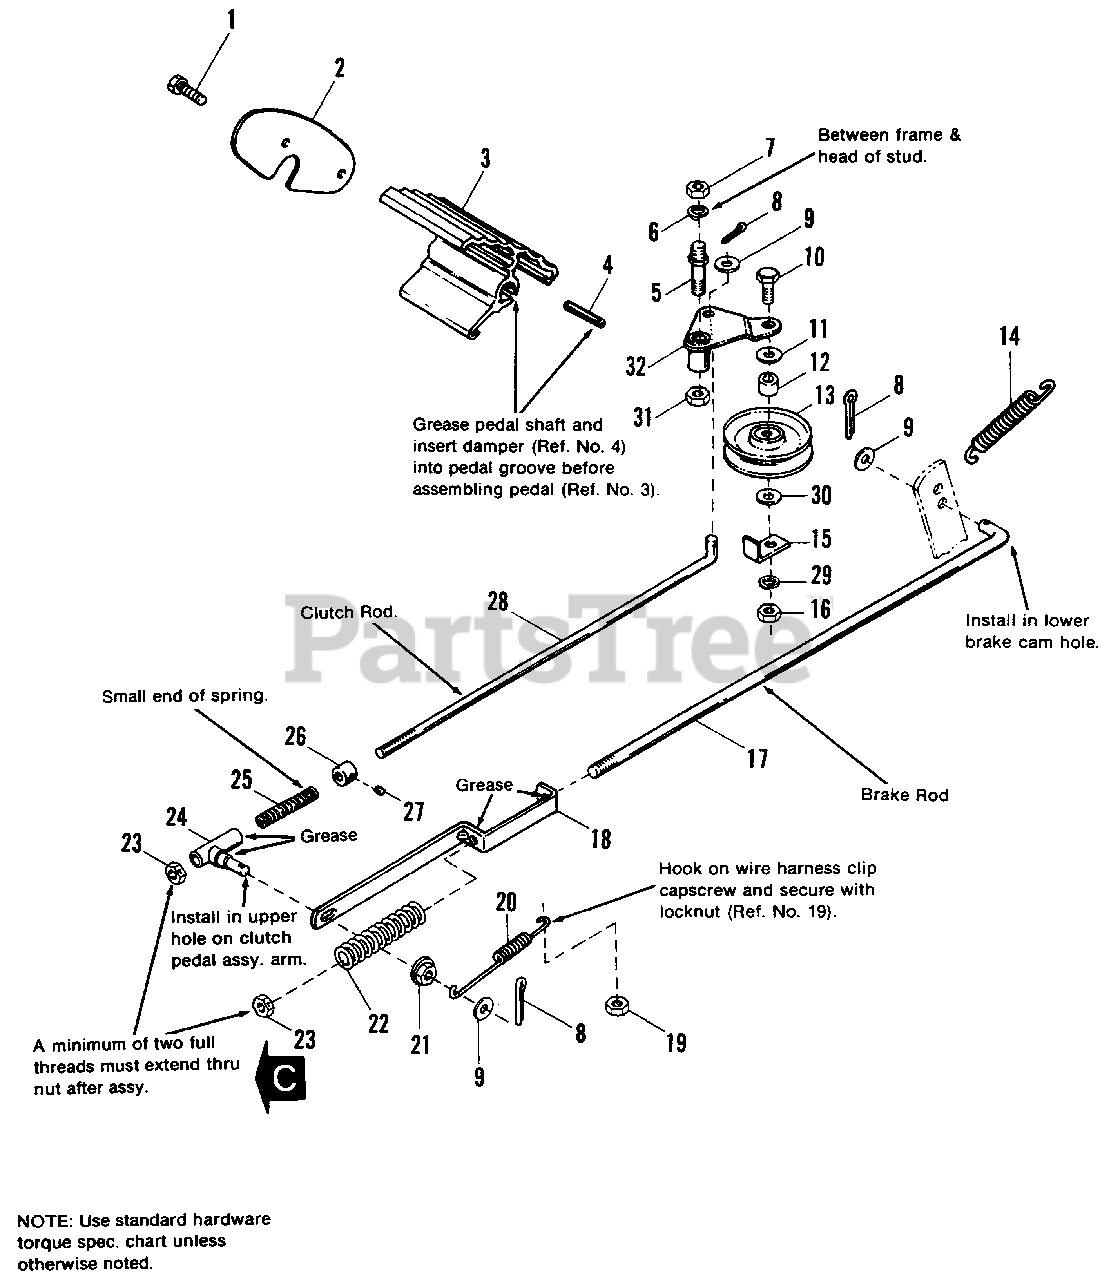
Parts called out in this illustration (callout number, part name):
1	SCREW, Hex, Taptite, 1/4-20 x 5/8
2	PLATE, End
3	PEDAL, Foot
4	DAMPER, Rubber
6	LOCKWASHER, 7/16
7	NUT, Hex, Full, 7/16-14
8	PIN, Cotter, 3/32 x 3/4
9	WASHER, Plain, 1/4
10	CAPSCREW, Hex Hd., 3/8-16 x 1-1/2
11	WASHER, Plain, 3/8
13	PULLEY ASSY. (Incl. Ref. No. 12)
14	SPRING, Tension
15	GUIDE, Belt
16	NUT, Hex, Full, 3/8-16
19	LOCKNUT, Hex, 5/16-18
20	SPRING, Return
21	LOCKNUT, Hex, Flange, 5/16-18
23	LOCKNUT, Hex, Esna, 5/16-18
24	GUIDE ASSY., Rod
25	SPRING, Compression
26	COLLAR, Set
27	SETSCREW. 1/4-20 x 3/8
28	ROD, Clutch
29	LOCKWASHER, 3/8
30	WASHER, Plain, 5/16
31	LOCKNUT, Hex, 7/16-14
32	IDLER ASSY.
